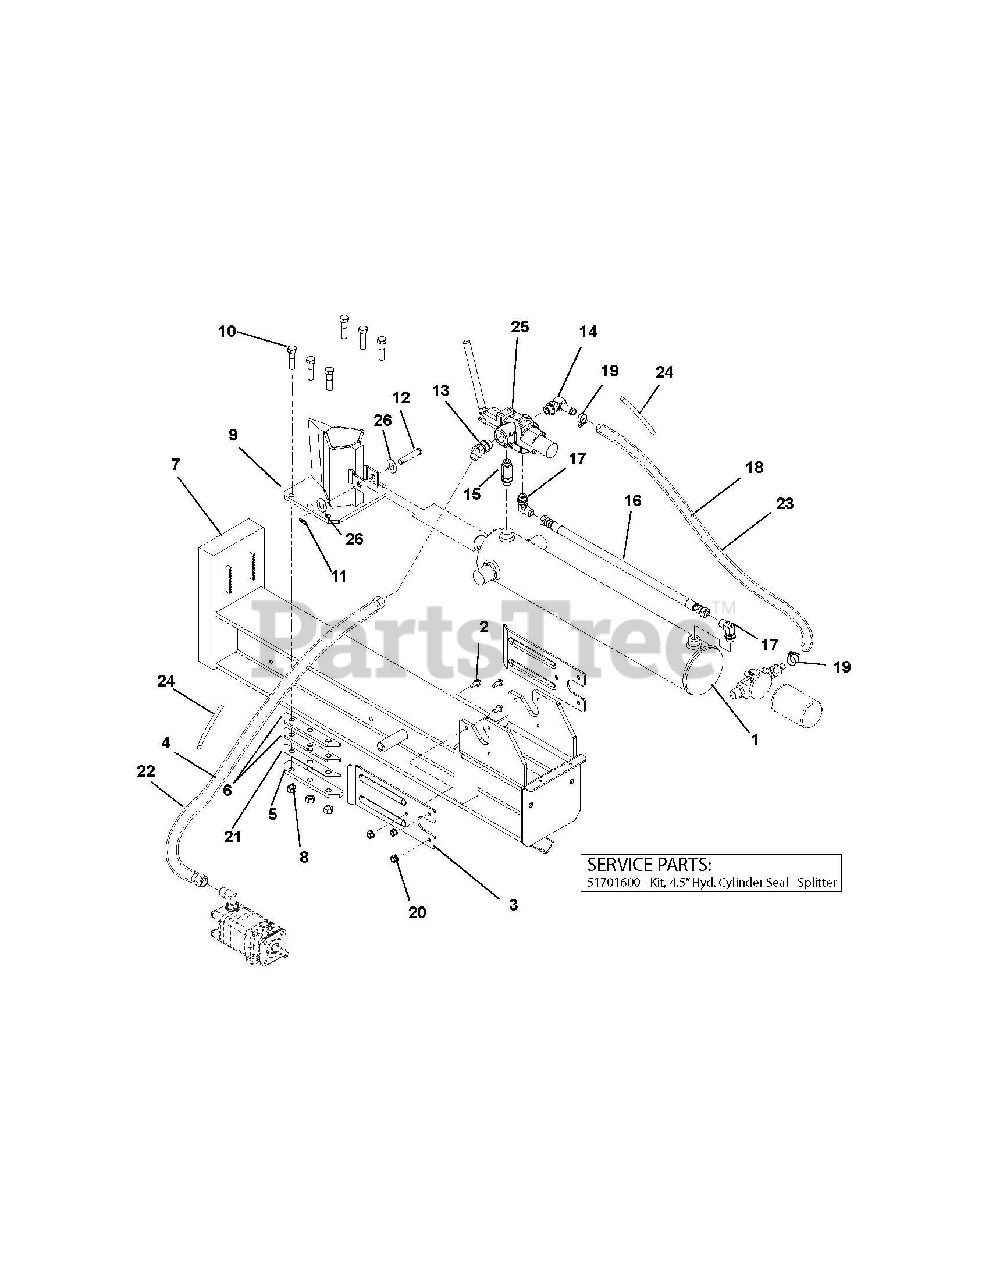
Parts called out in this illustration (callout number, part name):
1	Cylinder, 4.5-Inch With Decals
1	Kit, 4.5" Hydraulic Cylinder Seal - Splitter
2	Bolt, Hex .31-18 x 1.00
3	Plate, Stripper
4	Hose Assembly, 8M3K-8FJX-8FJX-46
5	Retainer, Wedge
6	Spacer, Wedge
7	Weldment, CE Splitter Beam
8	Nut, Locking Center .50-13
9	Weldment, Splitter Wedge
10	Bolt, Round Head Square Neck .50-13 x 2.00 Grade 8
11	Clip, Spring
12	Pin, Clevis .494 x 2.50, Bright Zinc Plating
13	Fitting, Hydraulic 6802-8-10
14	Fitting, Hydraulic 4601-10-10
15	Fitting, Hydraulic 6403-NWO-8-8-L
16	Hose Assembly, 8M3K-8FJX-8FJX-22
17	Fitting, Hydraulic 6801-8-8
18	Hose, Hydraulic Return 10LOLA x 53-In.
19	Clamp, .88 Diameter
20	Nut, Locking Top Flange .31-18
21	Shim, Splitter Wedge
22	Sleeve, Protective 50"
23	Sleeve, Protective 24"
24	Cable Tie
25	Valve, Control – CE Splitter
26	Washer, Flat Steel .563 x 1.38 x .109
